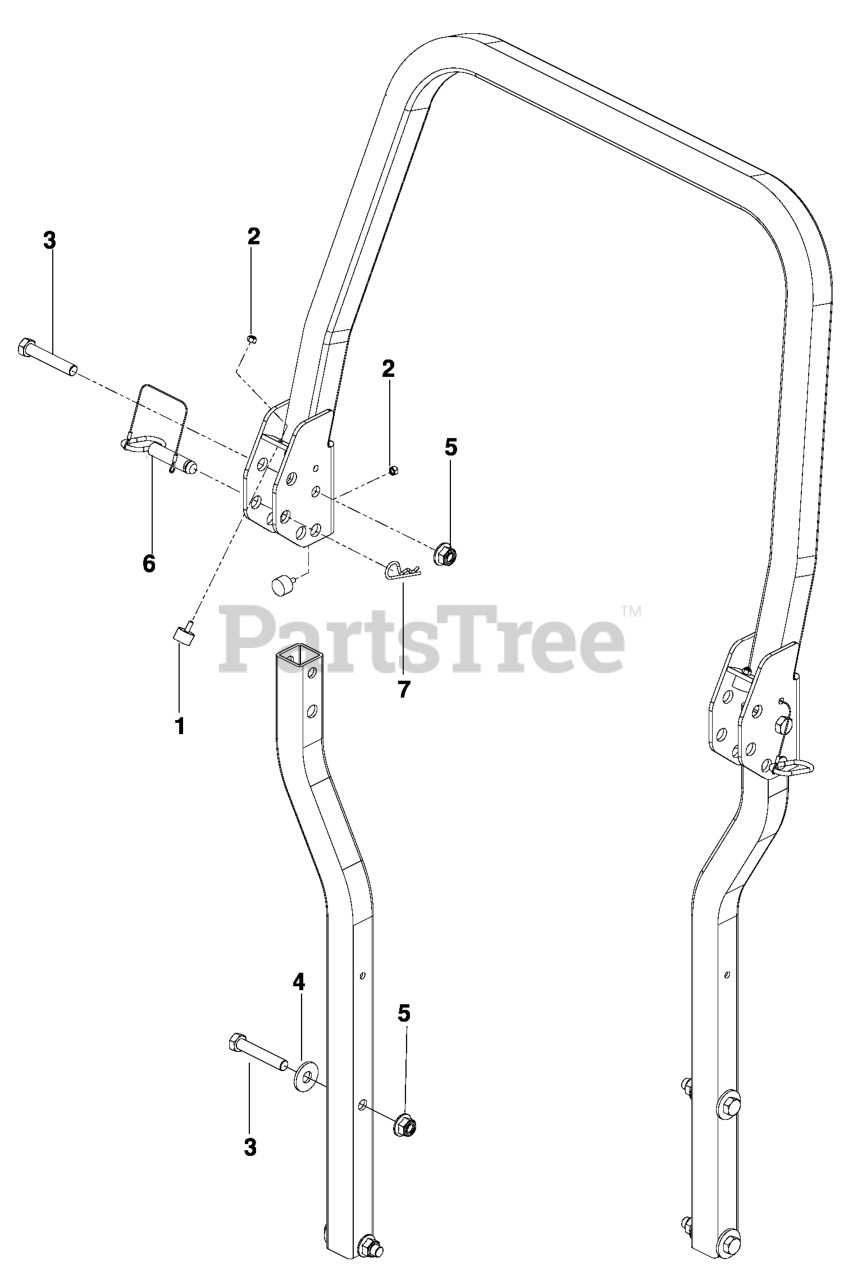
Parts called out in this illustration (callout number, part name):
1	BUMPER, MALE STUD, 1/4-20
2	NUT.1/4-20.HEX.NYLOC.ZD
3	5/8-11 X 3-1/2 HHB GRADE 5
4	WASHER, 5/8 FLAT
5	NUT 5/8-11 FLG NYLOC ZD
7	PIN HAIR .148 X 2-15/16 #210
